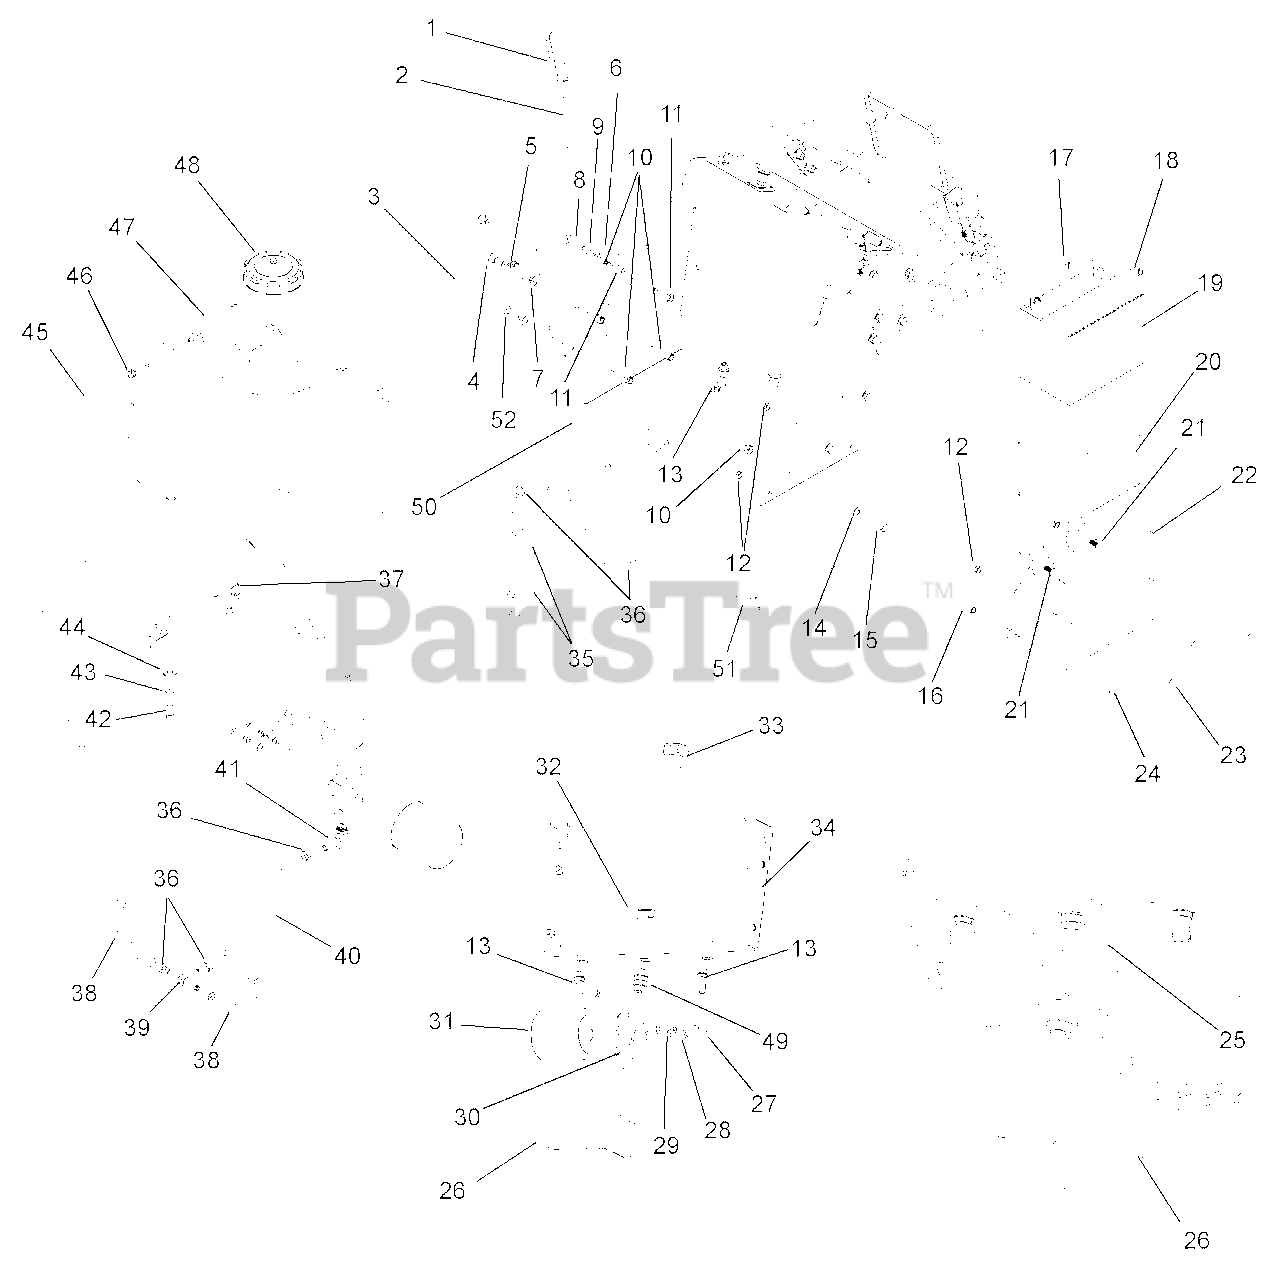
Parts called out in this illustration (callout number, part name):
1	GRIP, PVC .250 X 1.00 X 3.63
2	LEVER, HAND BRAKE FLOAT WALK
3	ROD, DRIVE CONTROL FW
4	BOLT, 1/2 X 1.06 X 3/8-16 SLD 5 Y
5	RING, RUE .375 X .054 x 1.254
6	LOCATOR, BRAKE ARM WD
7	WASHER, .510 X 1.00 X .068 NYLON
8	BOLT, 3/8-16 X 1.50 HEX 5 Y
9	LOCKNUT, 3/8-16 WHIZ Y
10	LOCKNUT, 3/8-16 NYLOC Y
11	LOCKNUT, 3/8-16 CENTER Y
12	LOCKNUT, 5/16-18 NYLOC Y
13	FTG, 90 9/16 MOR X 3/8 HOSE
14	WASHER, .406 X .813 X .065 FLAT Y
15	BOLT, 3/8-16 X 1.00 HEX 5 Y
16	BUSHING, .364X.540X.700 Y
17	LOCKNUT, 1/4-20 WHIZ Y
18	BOLT, 1/4-20 X .625 WSH Y
19	BATTERY, 12V-U1-CCA270MIN
20	STRIP, BATTERY INSULATOR
21	BOLT, 5/16-18 X .750 CRG 5 Y
22	TRAY, BATTERY 1948 HYDRO
23	BOLT, 5/16-18 X 6.00 CRG 2 Y
24	BOLT, 5/16-18 X 1.50 CRG 2 Y
25	BRACKET, FUEL TANK RMHF
26	GUARD, HYDRO FILTER FLWLK
27	BOLT, 1/4-20 X 1.00 HEX 5 Y
28	WASHER, .250 MED SPRG LOCK Y
29	WASHER, .250 REG FLAT Y
30	HEAD, OIL FILTER
31	FILTER, OIL
32	DECAL, WARNING - HOT SURFACES
33	CAP, OIL FILL BREATHER
34	WLDT, TANK
35	HOSE, HYD .375 X 10
36	CLAMP, HOSE - 1/2" PINCH
37	CABLE TIE, .15 X 8.50
38	HOSE, HYD 3/8 X 6.00
39	FTG, TUN 3/8 HOSE
40	HOSE, HYD. .375 X 9
41	FTG, 90 BRB-OR 4601-06-08
42	BOLT, 3/8-16 X .750 HEX 5 Y
43	WASHER, .375 MED SPRG LOCK Y
44	WASHER, .375 REG FLAT Y
45	HOSE, FUEL 1/4 X 30.00
46	CLAMP, HOSE - 1/2" SPRING
47	TANK, FUEL GRAVELY WALK REV G
48	CAP, FUEL
49	STRAIGHT UNION SAE 8
50	WLDT, RH UPRIGHT WD WALK
51	WLDT, LH UPRIGHT WD WALK
52	BOLT, 3/8-16 X 1.25 HEX 5 Y
